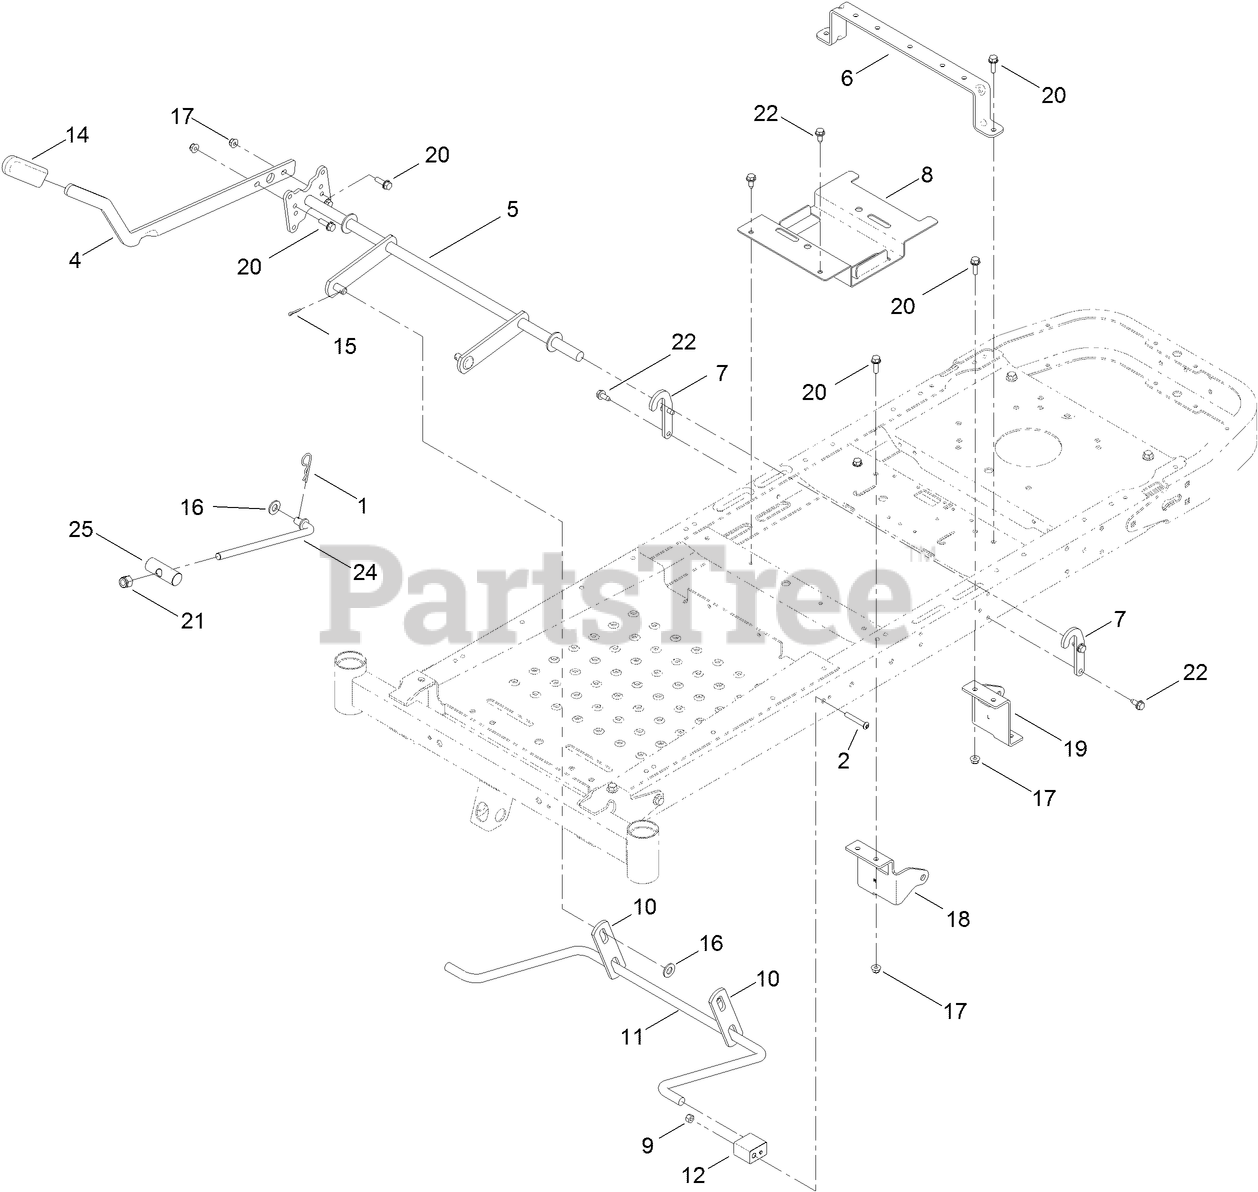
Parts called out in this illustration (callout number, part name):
1	PIN-COTTER
2	SCREW-HSBH
4	LEVER-LIFT
6	BRACE-SEAT, REAR (NARROW)
7	BRACKET-LIFT
8	BRACKET-BATTERY
9	NUT-LOCK, NI
10	LINK-LIFT
11	ARM-LIFT, REAR
12	BLOCK-PIVOT
14	GRIP-LEVER
15	PIN-COTTER
16	WASHER-FLAT
17	NUT-HF, NI
18	MOUNT-HYDRO, FRONT (RH)
20	SCREW-HHF
21	NUT-HEX
22	SCREW-HWHTF
25	PIN-PIVOT
